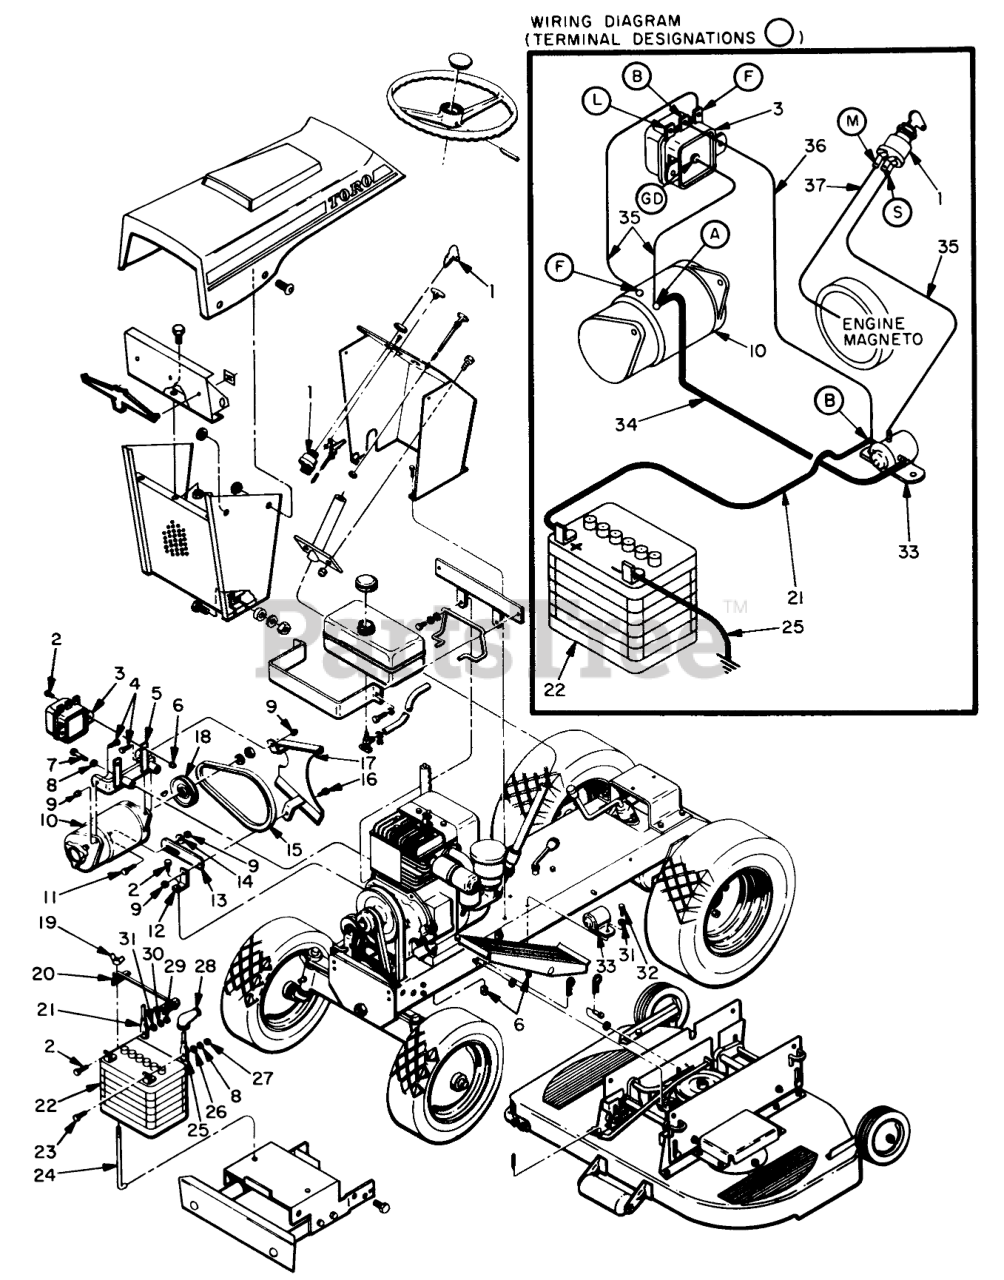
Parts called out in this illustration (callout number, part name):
1	Starter Switch
2	SCREW-HH
3	Voltage Regulator
4	SCREW-HH
5	Generator Bracket
6	Nut
7	SCREW-HH
8	WASHER-LOCK
9	Conelok Nut
10	Starter-Generator
11	SCREW-HH
13	Adjusting Arm
14	WASHER-FLAT
15	Belt, 3V 320
16	SCREW-HH
17	Belt Guard
19	NUT-WING
20	Battery Clamp
21	Black Wire
22	Battery
23	SCREW-HH
24	BATTERY BOLT
25	Black Wire
26	Washer
27	NUT-HEX
28	Terminal Boot
29	NUT-HEX
30	WASHER-LOCK
31	Flatwasher
32	SCREW-HH
33	Solenoid
34	Red Wire
35	Red Wire
36	Yellow Wire
37	Blue Wire
